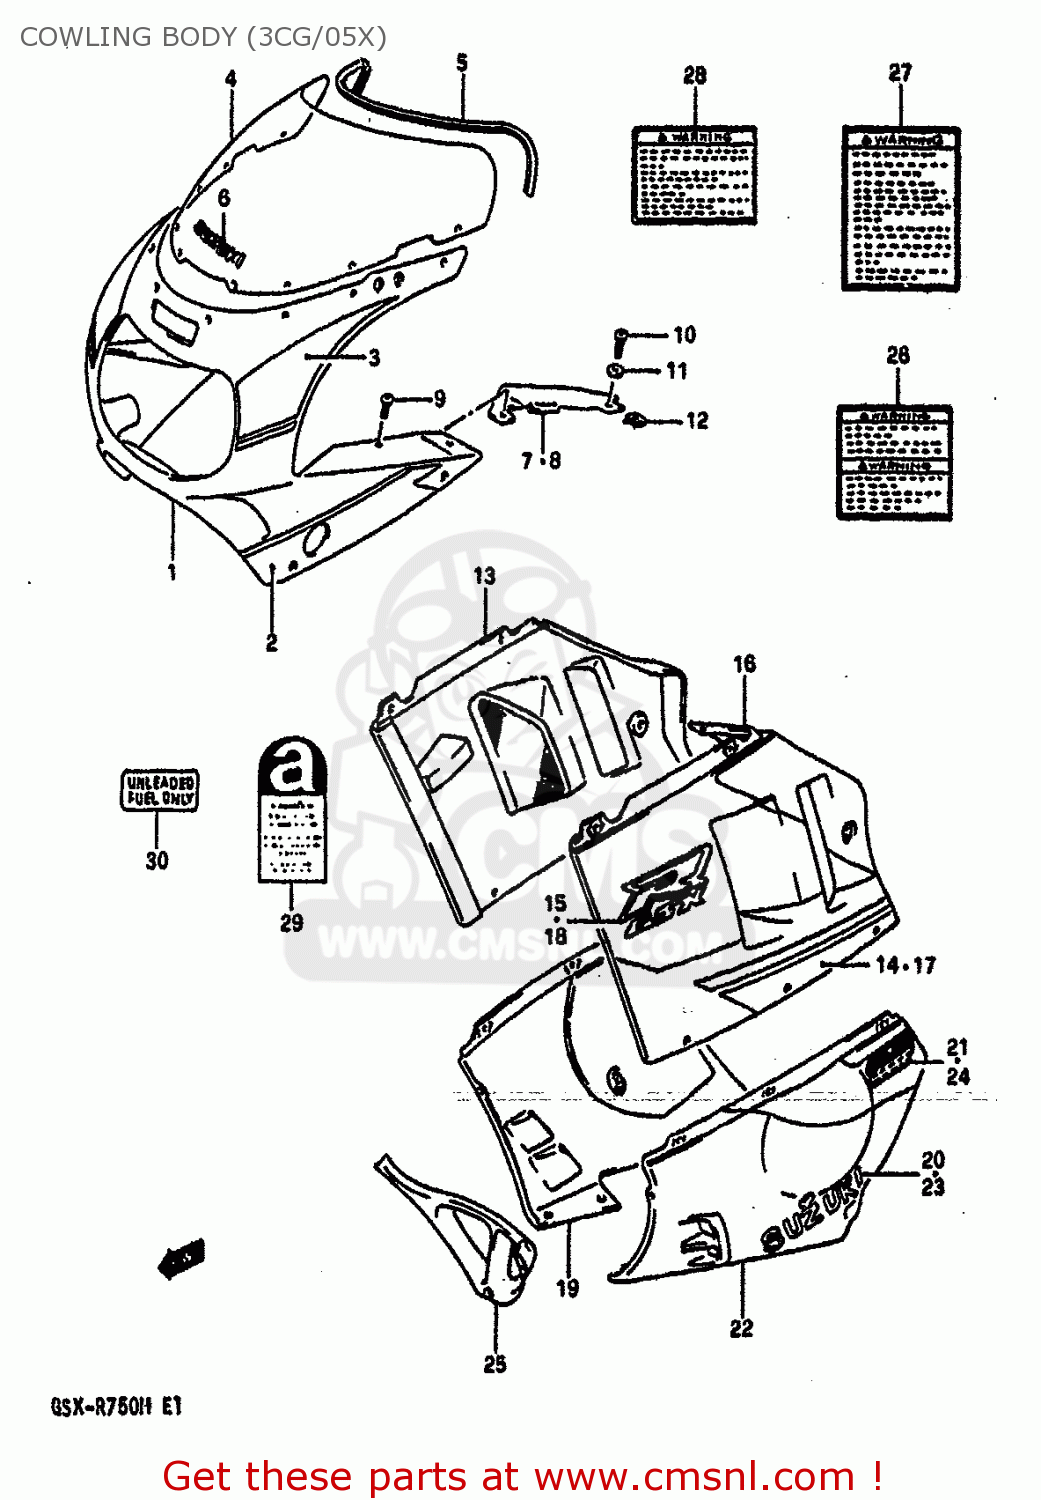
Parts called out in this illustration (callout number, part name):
1	BODY ASSEMBLY,COWLING
2	TAPE SET,SIDE
3	TAPE SET,COWL UPR FR
4	SCREEN SET,WIND
5	MOLDING
6	EMBLEM,SUZUKI(WHITE)
7	PANEL,COWLING UPR,R
8	PANEL,COWLING,UPPER,LEFT
9	SCREW(5X10)
10	SCREW(5X14)
11	WASHER(5.2X11X1)
12	NUT
13	COVER,COWLING SIDE,RIGHT
14	TAPE,SISE RH
15	EMBLEM,COWLING SIDE
16	COVER,COWLING SIDE,LEFT
17	TAPE,SIDE LH
18	EMBLEM,COWLING SIDE
19	COWLING,UNDER TH (BLACK/SILVER)
20	EMBLEM,COWLING,UNDER,RIGHT
21	EMBLEM,SACS
22	COWLING,UNDER
23	EMBLEM
24	EMBLEM,SACS
25	COWLING,UNDER,CENTER (B
26	LABEL (WARNING)
27	LABEL (WARNING SCREEN)
28	LABEL, WARNING SAFETY
29	LABEL,ASBESTOS WARNING
30	LABEL,FUEL CAUTION
